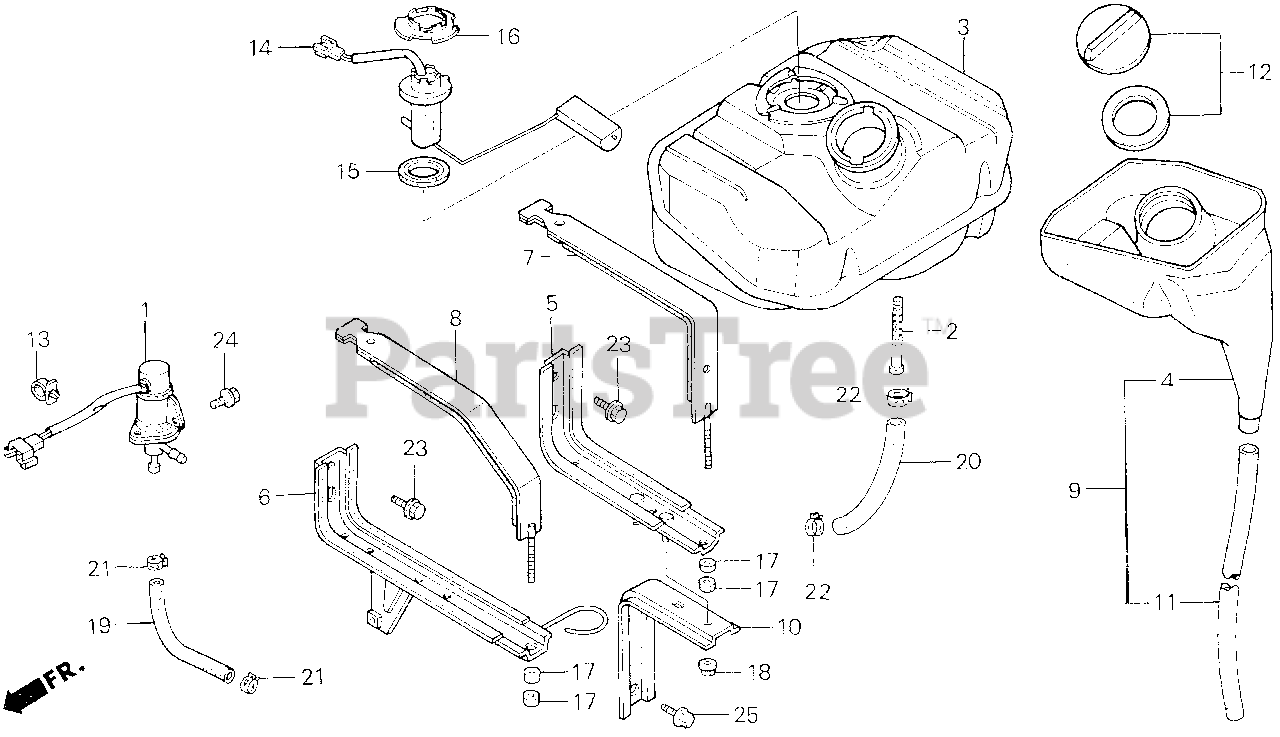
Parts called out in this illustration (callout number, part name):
1	VALVE ASSY., ELECTRIC FUEL
2	FILTER, FUEL
3	TANK, FUEL
4	TRAY, FUEL TANK
5	STAY A, TANK
6	STAY B, TANK
7	BAND A, TANK
8	BAND B, TANK
9	TUBE, FUEL TANK TRAY DRAIN
10	BEAM, TANK BRACKET
11	TUBE, DRAIN
12	CAP, FUEL TANK
13	CLIP, IGNITION WIRE (8MM)
14	METER UNIT, FUEL
15	GASKET, BASE
16	RETAINER, FUEL UNIT
17	NUT, HEX. (6MM)
18	NUT, FLANGE (6MM)
19	BULK HOSE, FUEL (5.5X8000) (5.5X160)
20	BULK HOSE, FUEL (7.5X3000) (7.3X150)
20	BULK HOSE, FUEL (8X1000) (8X150)
21	CLAMP, TUBE (D10.5)
22	CLAMP, TUBE (D13)
23	BOLT, FLANGE (6X10)
24	BOLT, FLANGE (6X12)
25	BOLT, FLANGE (8X14)
